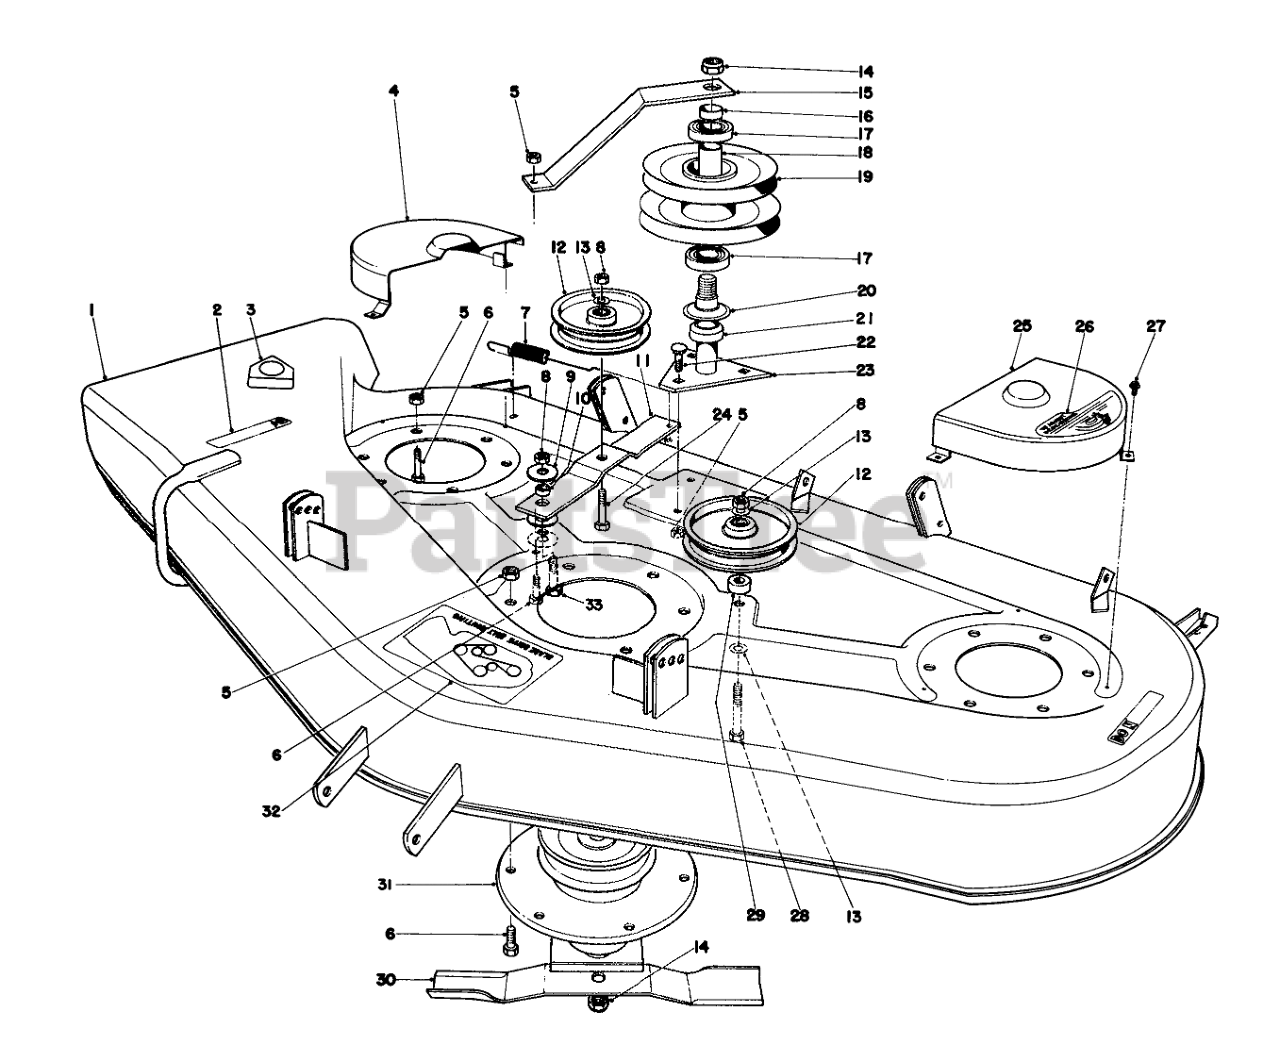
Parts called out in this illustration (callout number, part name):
1	42 IN DECK WA B
2	DECAL-NO STEP
3	DECAL-DANGER
4	RH BELT COVER WA B
5	NUT-LOCK, CONE
6	SCREW-HH
7	EXT SPRING O
8	NUT-LOCK, CONE
9	WASHER
10	IDLER BRKT SPACER
11	Idler Pulley Bracket
12	PULLEY-IDLER
13	WASHER-FLAT
14	NUT-LOCK, NI
15	Support Spindle
16	SPACER
17	BEARING
18	SPACER
19	Pulley & Bearing Assembly
20	DUST COVER
21	SPACER
22	BOLT-CARR
23	SHAFT SADDLE ASM
24	SCREW-HH
25	LH BELT COVER WA B
26	WHEEL ADJ DECAL
27	SCREW-HWHTF
28	SCREW-HH
29	SPACER O
30	Blade
31	Spindle ASM
32	Decal Belt Routing
33	SCREW-HH
